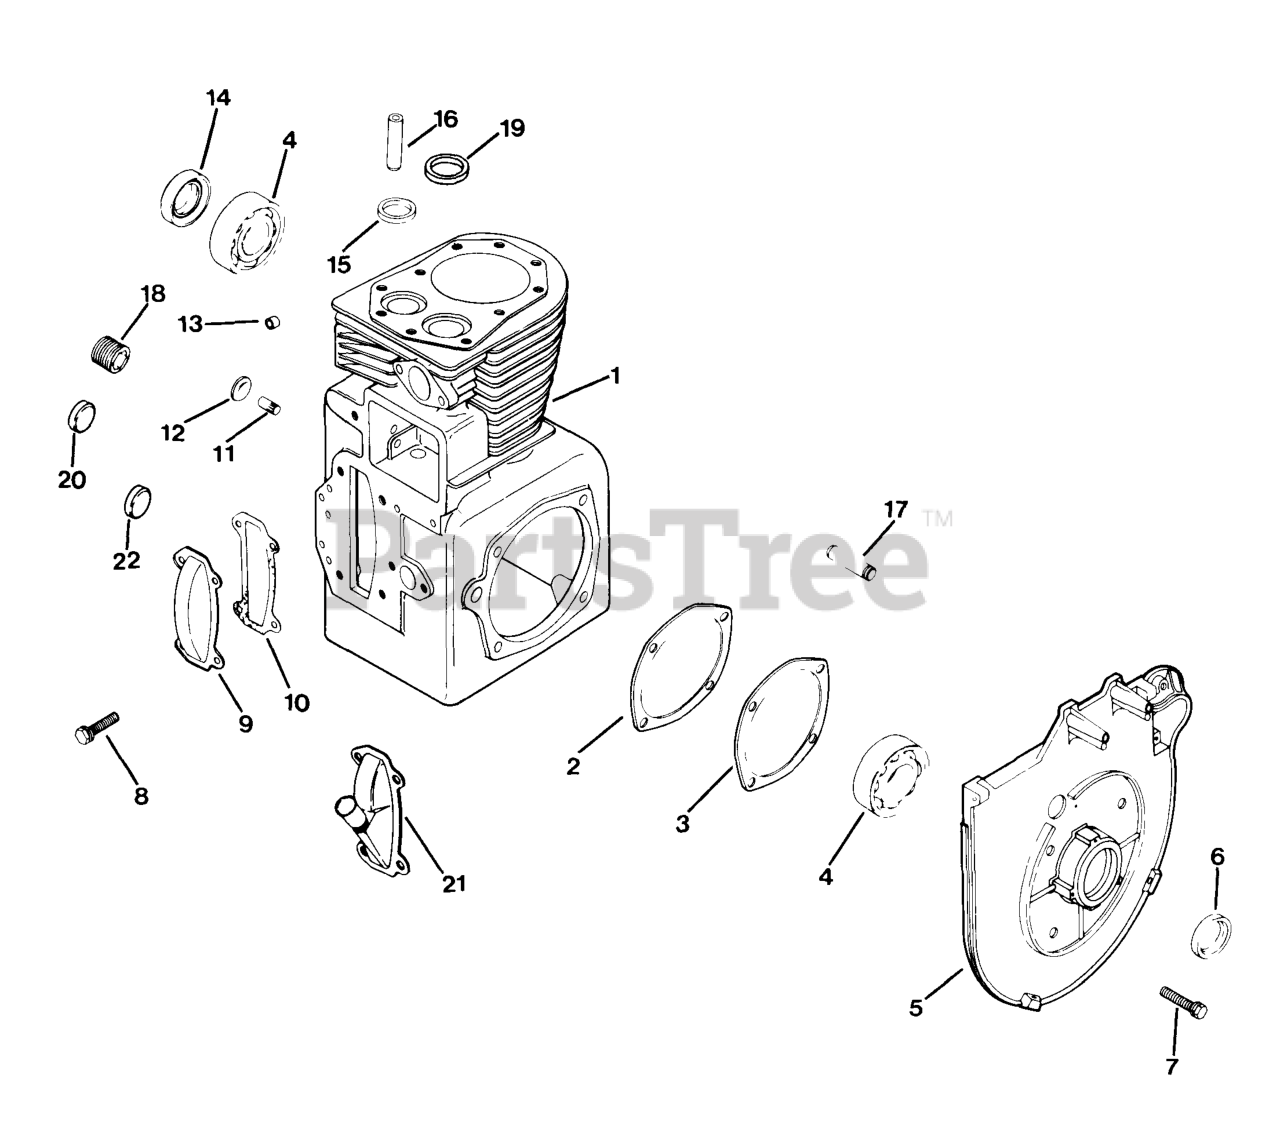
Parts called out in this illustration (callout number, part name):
1	Cylinder block
3	GASKET, BEARING PLATE - DISCONTINUED
4	BEARING, BALL
5	PLATE - USE 47 146 11
6	SEAL, FRONT OIL
7	SCREW, SEMS 3/8-16-X1"
8	SCREW, SEMS 1/4-20X5/8" USE 25 086 539-S
9	COVER, CAMSHAFT - DISCONTINUED
10	GASKET, CAMSHAFT COVER
11	SHAFT, GOVERNOR GEAR
12	PLUG, WELCH EXPANSION
13	BEARING
14	SEAL, REAR OIL
15	INSERT - DISCONTINUED
16	GUIDE, VALVE - DISCONTINUED
